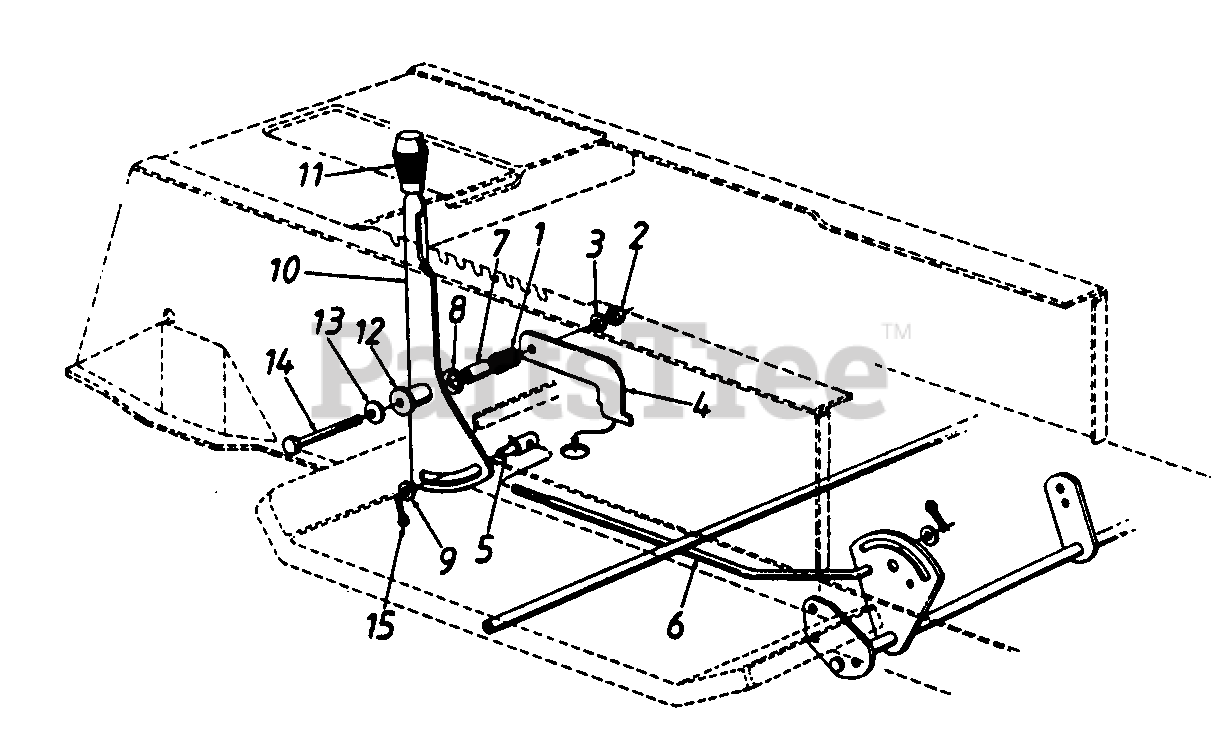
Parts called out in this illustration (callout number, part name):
1	Compression Spring
2	Hex Nut 5/16-18 Thd.
3	L-Wash. 5/16" I.D.
4	Shift Lever Support
5	Ferrule 3/8-24 Thd.
6	Speed Control Rod
7	Spacer 1.15" Lg.
8	Bell-Wash. .505" I.D. x 1
9	Fl-Wash. .385" I.D. x .87"
10	Speed Selector Lever
11	Shift Knob
12	Spacer 1.46" Lg.
13	Bell-Wash. .345" I.D. x .88"
14	Hex Bolt 5/16-18 x 3.25" Lg.
15	Cotter Pin 3/32" Dia. x 1"
